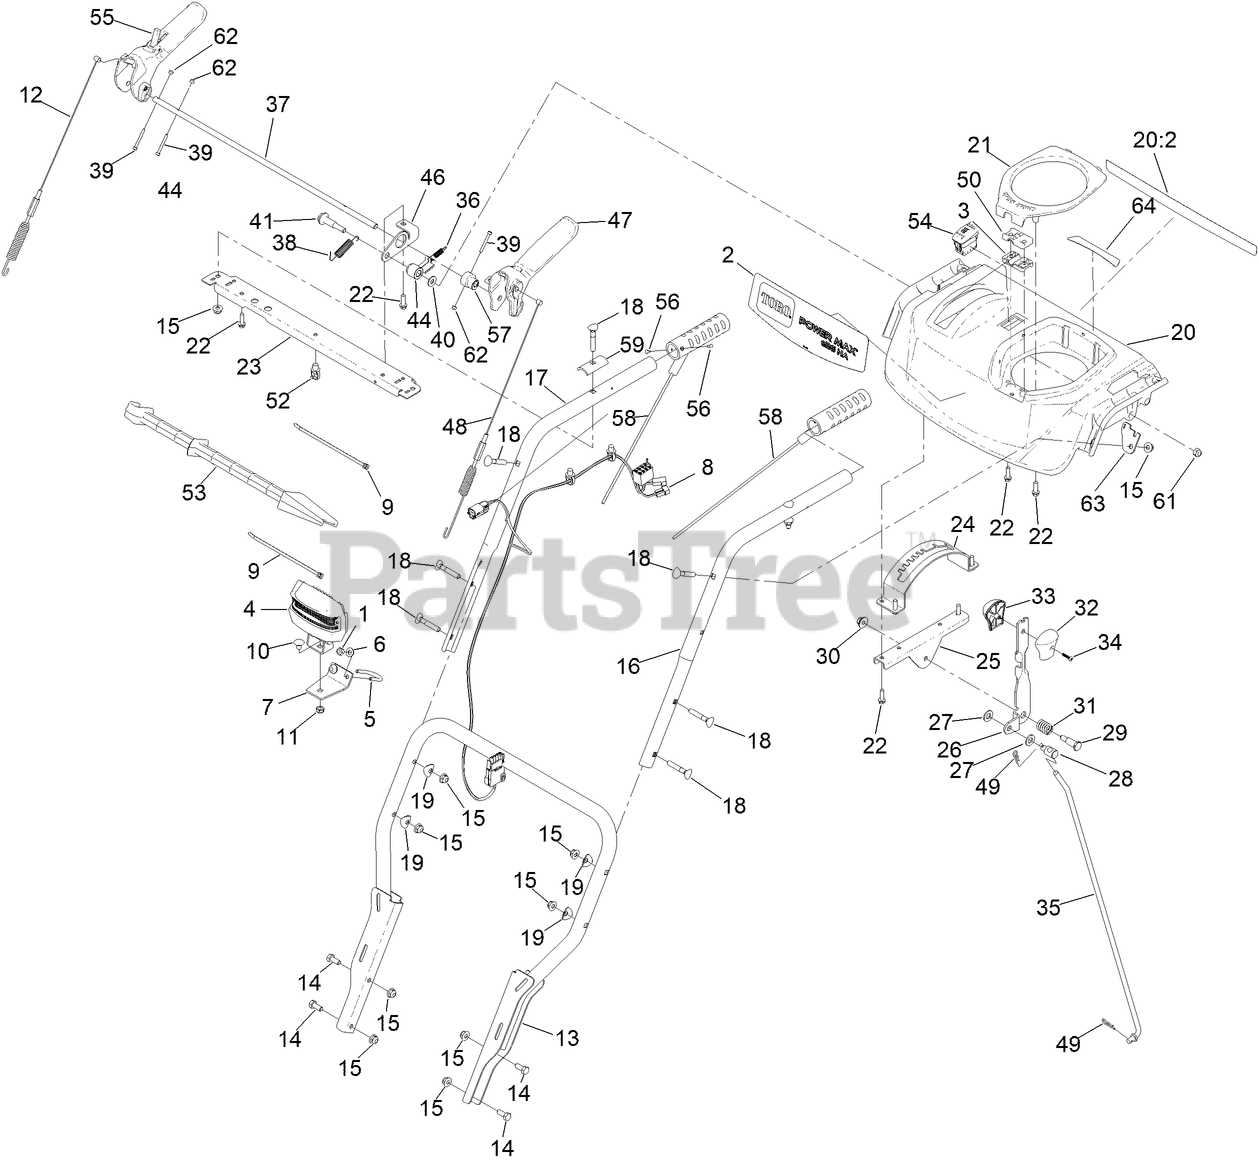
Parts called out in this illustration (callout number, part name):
1	NUT-HEX
2	DECAL - CONSOL
3	SUPPORT-ROD, LOWER
4	LED LIGHT ASM
5	CLAMP-LIGHT
6	WASHER-FLAT
7	BRACKET-LIGHT
8	HARNESS-WIRE, LED AND HAND WARMERS [60V]
9	TIE-CABLE
10	BOLT-CARR
11	NUT-HEX
12	CABLE-AUGER
13	HANDLE-LOWER
14	SCREW-HH
15	NUT-HF
16	HANDLE-UPPER, LH
17	HANDLE-UPPER, RH
18	SCREW-HANDLE
19	WASHER-CUP
20	CONTROL PANEL ASSEMBLY
20:2	DECAL-SAFETY
21	COVER-QUICKSTICK
22	SCREW-PLASTITE, HWH
23	BRACE-CONSOLE
24	GATE-SHIFT
25	BRACKET-SHIFT
26	SELECTOR-SPEED
27	WASHER-FLAT
28	TRUNNION-ROD
29	SCREW-SHOULDER, HH
30	NUT-HF
31	SPRING-COMPRESSION
32	KNOB-SHIFT, LH
33	KNOB-SHIFT, RH
34	SCREW-PPH
35	ROD-SHIFT
36	SPRING-LOCKOUT, HANDLE
37	ROD-LOCKOUT
38	SPRING-RETURN, LEVER
39	SCREW-HSH,SPL
40	WASHER-FLAT
41	SCREW-SHOULDER
44	LATCH, LOCKOUT
46	BRACKET-INTERLOCK
47	LEVER-CONTROL
48	CABLE-TRACTION
49	PIN-HAIR
50	SUPPORT-ROD, UPPER
52	CLIP-TIE
53	STICK-CLEANOUT
54	SWITCH-ROCKER, ON-NONE-OFF (HEATER)
55	AUGER CONTROL ASM
56	RIVET-POP
57	CAM-LOCKOUT
58	GRIP-HEATED
59	SADDLE-HANDLE
61	NUT-HEX
62	NUT-LOCK ROHS
63	PLATE-SPRING
64	DECAL - QUICK STICK
